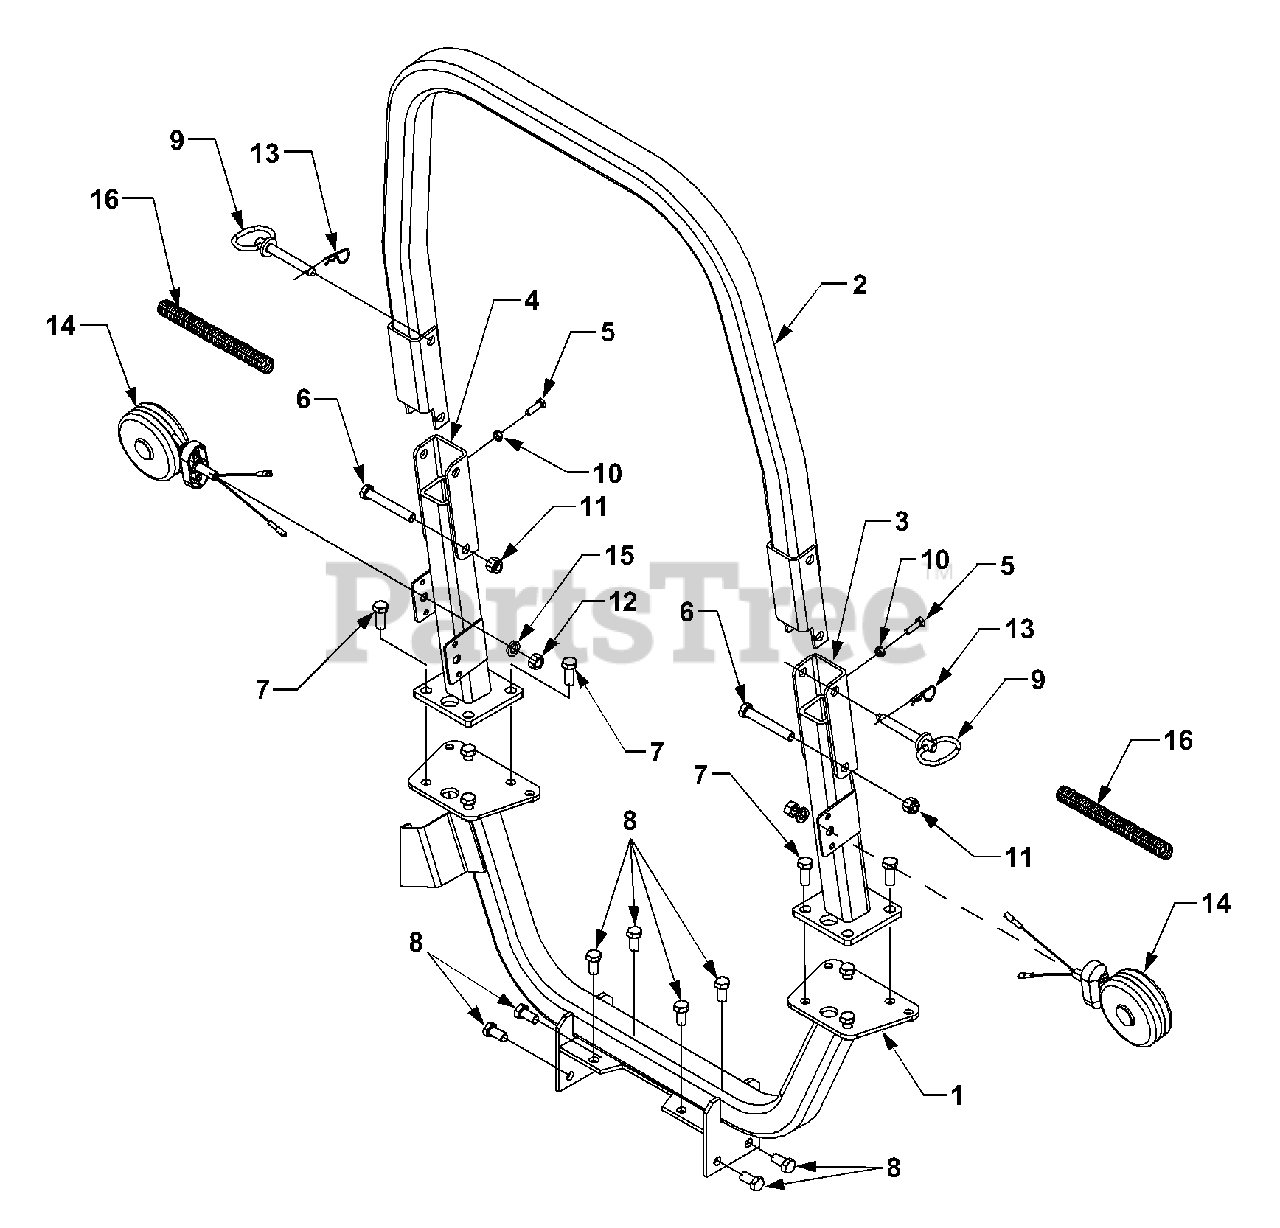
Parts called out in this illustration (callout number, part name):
1	ROPS Assembly, Lower
2	ROPS Assembly, Upper
3	Mounting Assembly, ROPS RH
4	Mounting Assembly, ROPS LH
5	Screw, Hex Cap, 5/16-18 x 1.0 GR5
6	Screw, Hex Cap, 1/2-20 x 3.5 GR5
7	Screw, Hex Cap, 1/2-13 x 1.25 GR5
8	Screw, Hex Cap, 1/2-13 x 1.0 GR5
9	Pin, Clevis, .5 x 3.5
10	Nut, Hex Jam, 5/16-18
11	Nut, Hex Nylon Insert Lock, 1/2-20
12	Nut, Hex, 1/2-20 GR5
13	Pin, Internal Cotter
14	Light Assembly, Hazard
15	Washer, Lock, 1/2
